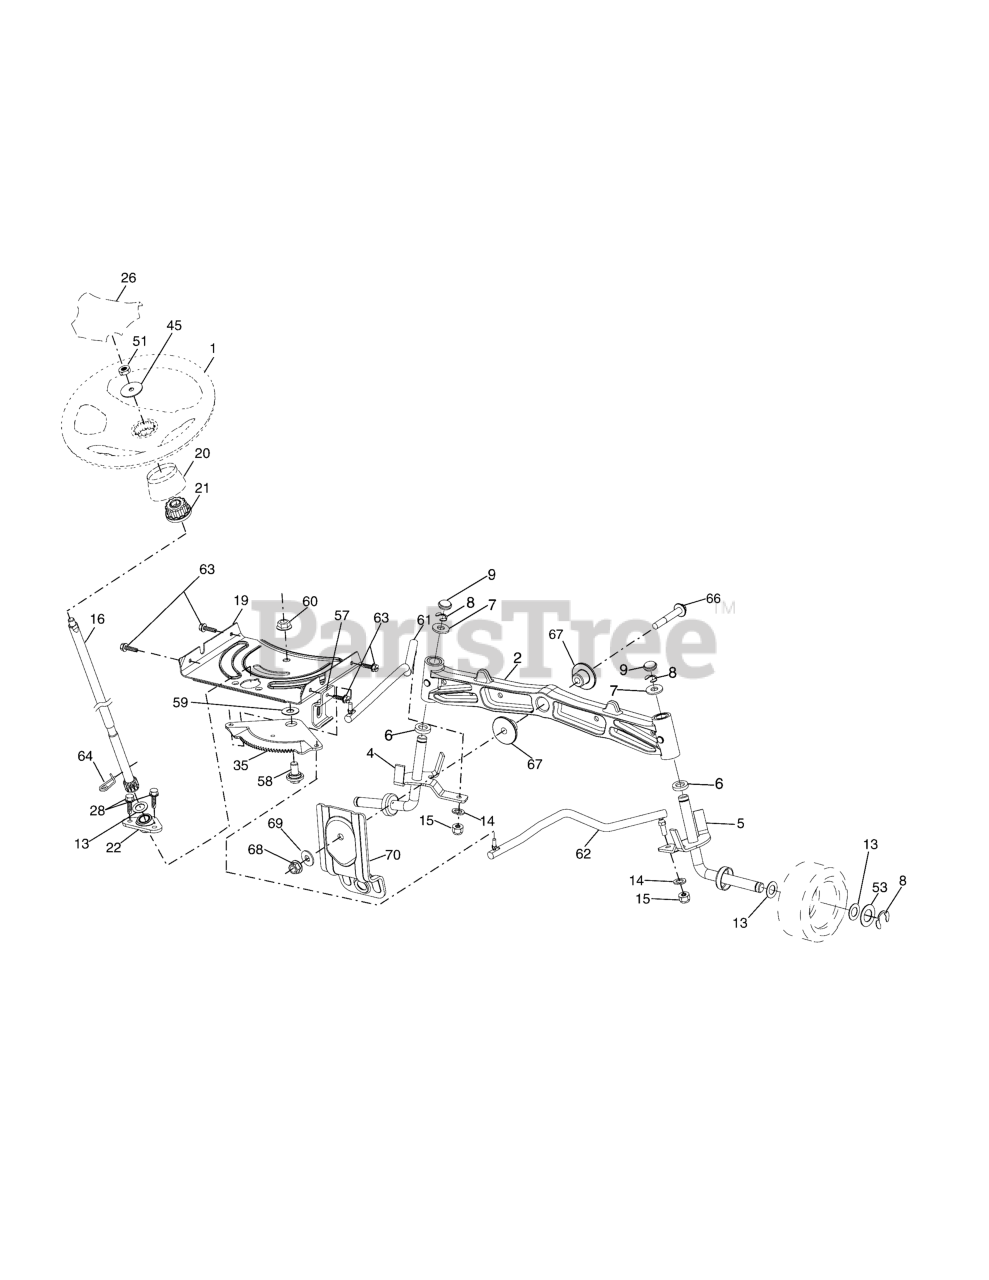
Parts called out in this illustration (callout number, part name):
1	Wheel, Steering
2	Axle Asm., Front
4	Spindle Asm., LH
5	Spindle Asm., RH
6	Bearing, Race Thrust Harden
7	Washer 25/32 x 1-5/8 x 16 Ga.
8	Ring, Clip #T5304-75
9	Cap, Spindle
13	Washer 25/32 x 1-1/4 x 16 Ga.
14	Washer, Lock Hvy Hlcl Spr 3/8
15	Nut, Crown Lock 3/8-24 unf
16	Shaft Steering
19	Plate Steering
20	Boot, Steering
21	Adapter, Wheel Steering
22	Strg. Supt. Lower
26	Insert, Wheel Steering
28	Screw 3/8-16 x 3/4
35	Gear, Sector Plate
45	Washer 11/32 x 2-3/8 x 12 Ga.
51	Nut Hex Jam Toplock 1/2-20 unf
53	Washer Hardened .793 x 1.637 x .060
57	Bracket Upstop
58	Bolt Shoulder Sector Pivot CFM
59	Washer Thrust Sector Steering
60	Nut Flange Lock 5/8-11
61	Draglink, LH
62	Draglink, RH
63	Screw 5/16-18 x 3/4
64	Retainer Clip Spring Steering
66	Bolt Hex Fghd 7/16-14 x 3 Serr
67	Bushing PM Front Axle
68	Nut Lock Flange 7/16-14 Gr. 5
69	Washer 1.5 x .505 x .118
70	Bracket Deck Susp. Front
